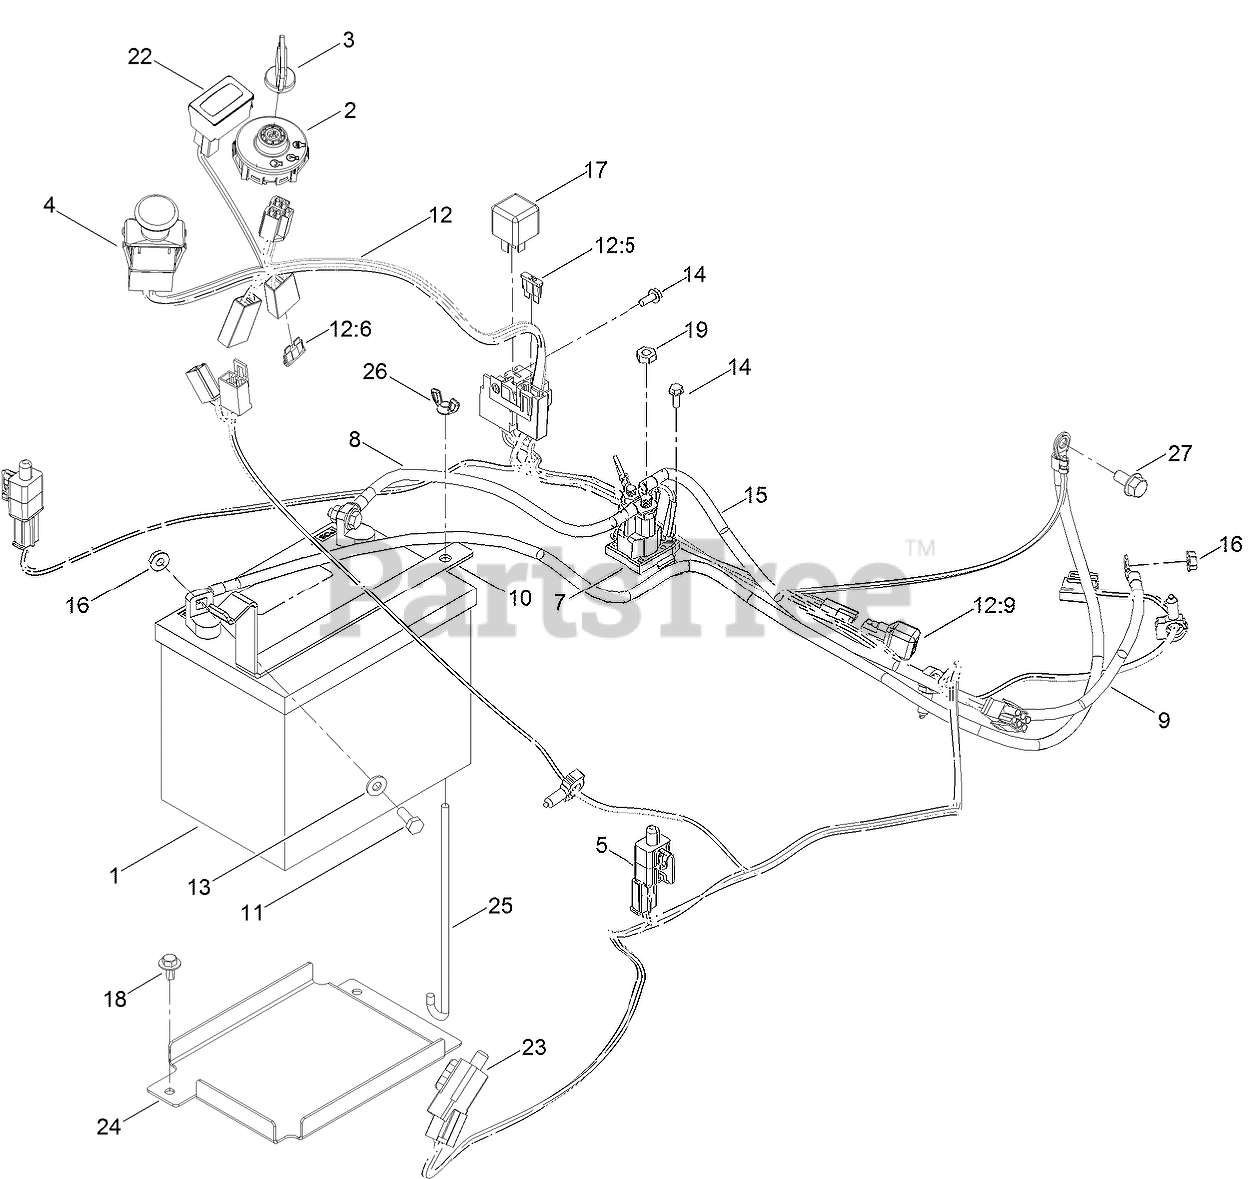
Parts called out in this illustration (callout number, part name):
1	BATTERY
2	SWITCH-IGNITION
3	KEY-IGNITION
4	SWITCH-PTO
5	SWITCH
7	SOLENOID
8	CABLE-BATTERY, POSITIVE
9	CABLE-BATTERY, NEGATIVE
10	STRAP-BATTERY
11	SCREW-HH
12	HARNESS-WIRE
12:5	FUSE-BLADE, 30 AMP
12:6	FUSE-BLADE, 25 AMP
13	WASHER-FLAT
14	SCREW-TAPTITE
15	WIRE-21 INCH
16	NUT-HF
17	RELAY
18	SCREW-HHFTF
19	NUT-JAM
22	HOURMETER
23	SWITCH-REVERSE
24	TRAY-BATTERY
25	BOLT-HOLDDOWN
26	WINGNUT
27	SCREW-HHF
